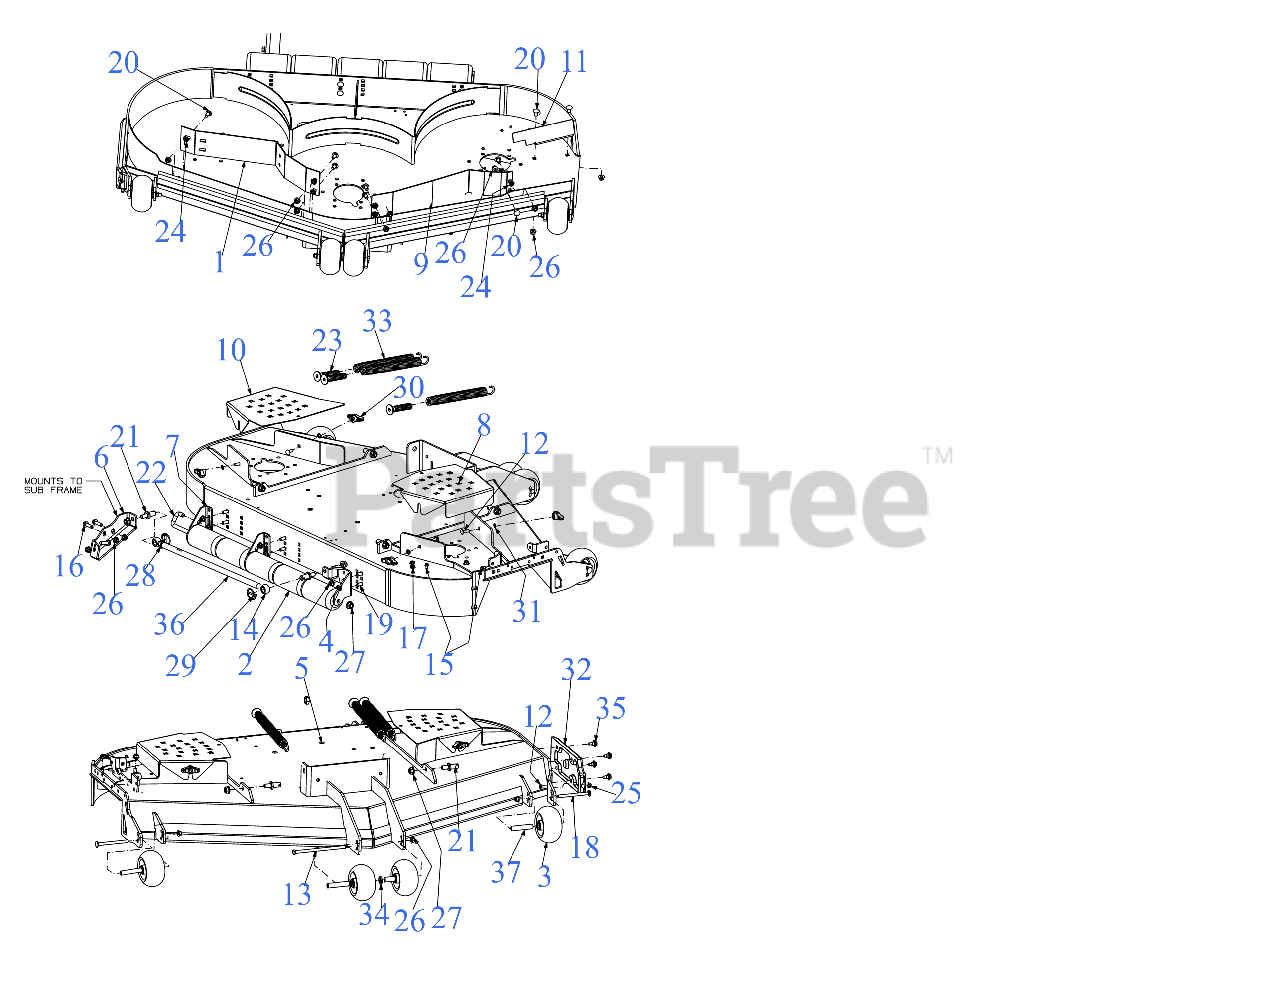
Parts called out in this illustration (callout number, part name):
1	BAFFLE - 60" ADJ
2	ROLLER ASSEMBLY
3	5" DIA DECK WHEEL COMPLETE
3	WHEEL BUSHING
6	STABILIZER MOUNTING BRACKET
12	CARRIAGE BOLT 5/16-18 x 1.00
13	SCREW 3/8-16 x 7.25 GR5
14	BOLT 5/8-16 x 2.63
15	SCREW 1/4-20 X.500
16	SCREW 3/8-16 x 1.25 GR5
17	SCREW 5/16-18 x .500
18	CARRIAGE BOLT 3/8-16 x 4.25 GR5
19	CARRIAGE BOLT 3/8-16 x 1.00 GR5
20	CARRIAGE BOLT 3/8-16 x .75
22	REAR ROLLER PIN
23	SPRING INSERT SCREW
25	FLANGE LOCK NUT 5/16-18
28	HEX JAM NUT
29	LYNCH PIN .1875
30	WING KNOB 5/16-18
32	DECK SKID PLATE (LH)
33	EXTENTION SPRING 1.20 x 11.35
34	FLAT WASHER .632X1.00X.16
35	SHOULDER SCREW .43X.29X5/16-18 TT
37	WHEEL SPACER .38ID x 3.04LG
